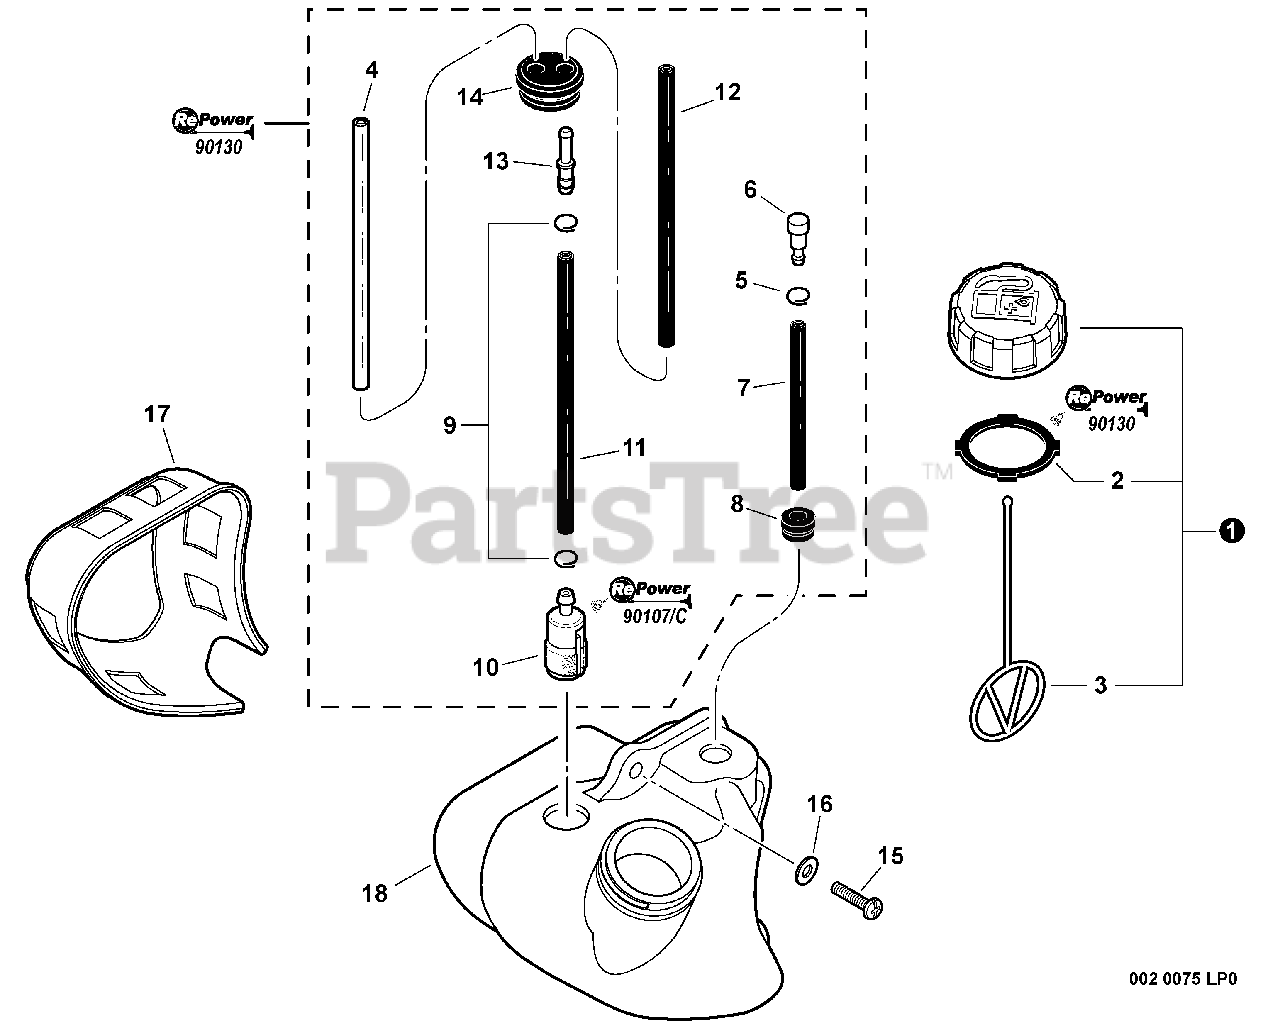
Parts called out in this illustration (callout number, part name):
1	CAP ASSY - ORANGE
2	GASKET, CAP
3	CONNECTOR, CAP
4	PIPE - 3X6X85 -- CLEAR
5	CLIP - 6
6	VENT, FUEL TANK
7	PIPE - 3X5X50 -- BLACK
8	GROMMET
9	CLIP - 6
10	FILTER, FUEL
11	PIPE - 3X5X90 -- BLACK
12	PIPE - 3X5X87 -- BLACK
13	CONNECTOR, PIPE
14	GROMMET
15	SCREW - 5X20 -- TAPPING
16	WASHER - 5
17	GUARD, FUEL TANK
18	TANK, FUEL
19	RePower FUEL SYSTEM KIT
20	RePower TUNE-UP KIT
